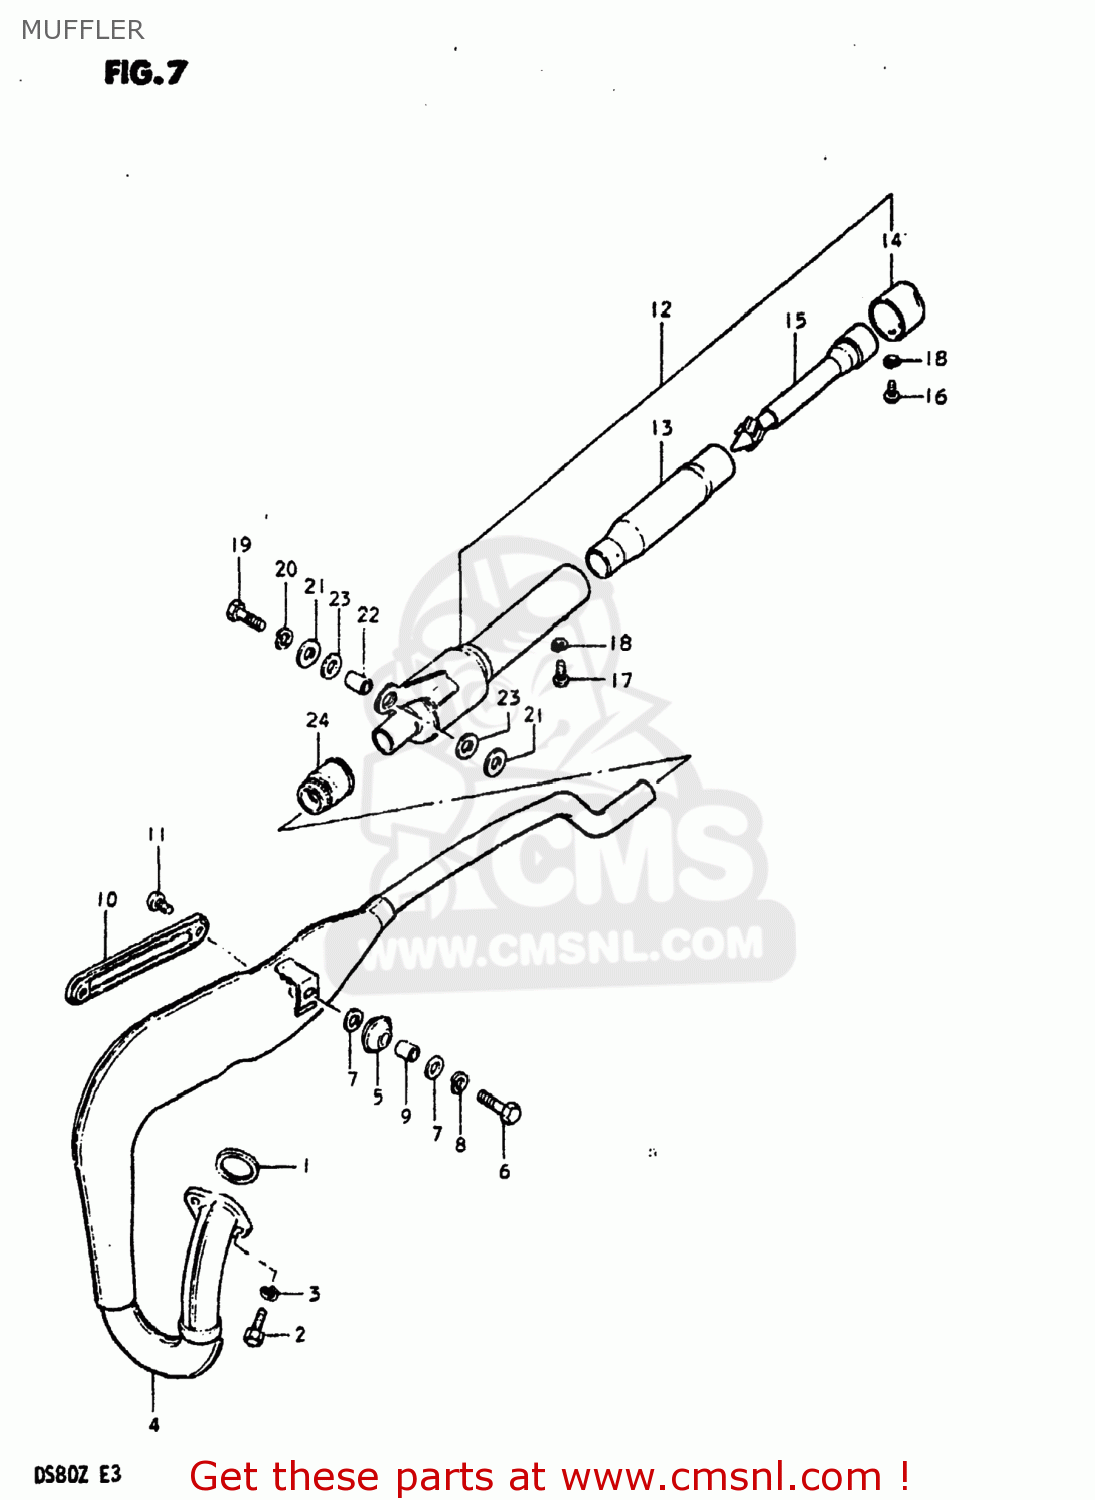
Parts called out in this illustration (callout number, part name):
1	GASKET,EXHAUST PIPE (NAS)
2	BOLT
3	LOCK WASHER
4	BODY,MUFFLER
5	DAMPER,MUFFLER,FR
6	BOLT (8X30)
7	WASHER
8	LOCK WASHER
9	SPACER (8X12X15)
10	COVER,MUFFLER
11	SCREW
12	MUFFLER ASSEMBLY
13	SHELL,ARRESTER
14	CUTTER,SPARK ARRESTER
15	TUBE,CLEAN OUT
16	SCREW
17	SCREW
18	LOCK WASHER
19	BOLT
20	LOCK WASHER
21	WASHER
22	SPACER (8.6X13.8X9)
23	CUSHION
24	CONNECTOR,MUFFLER
